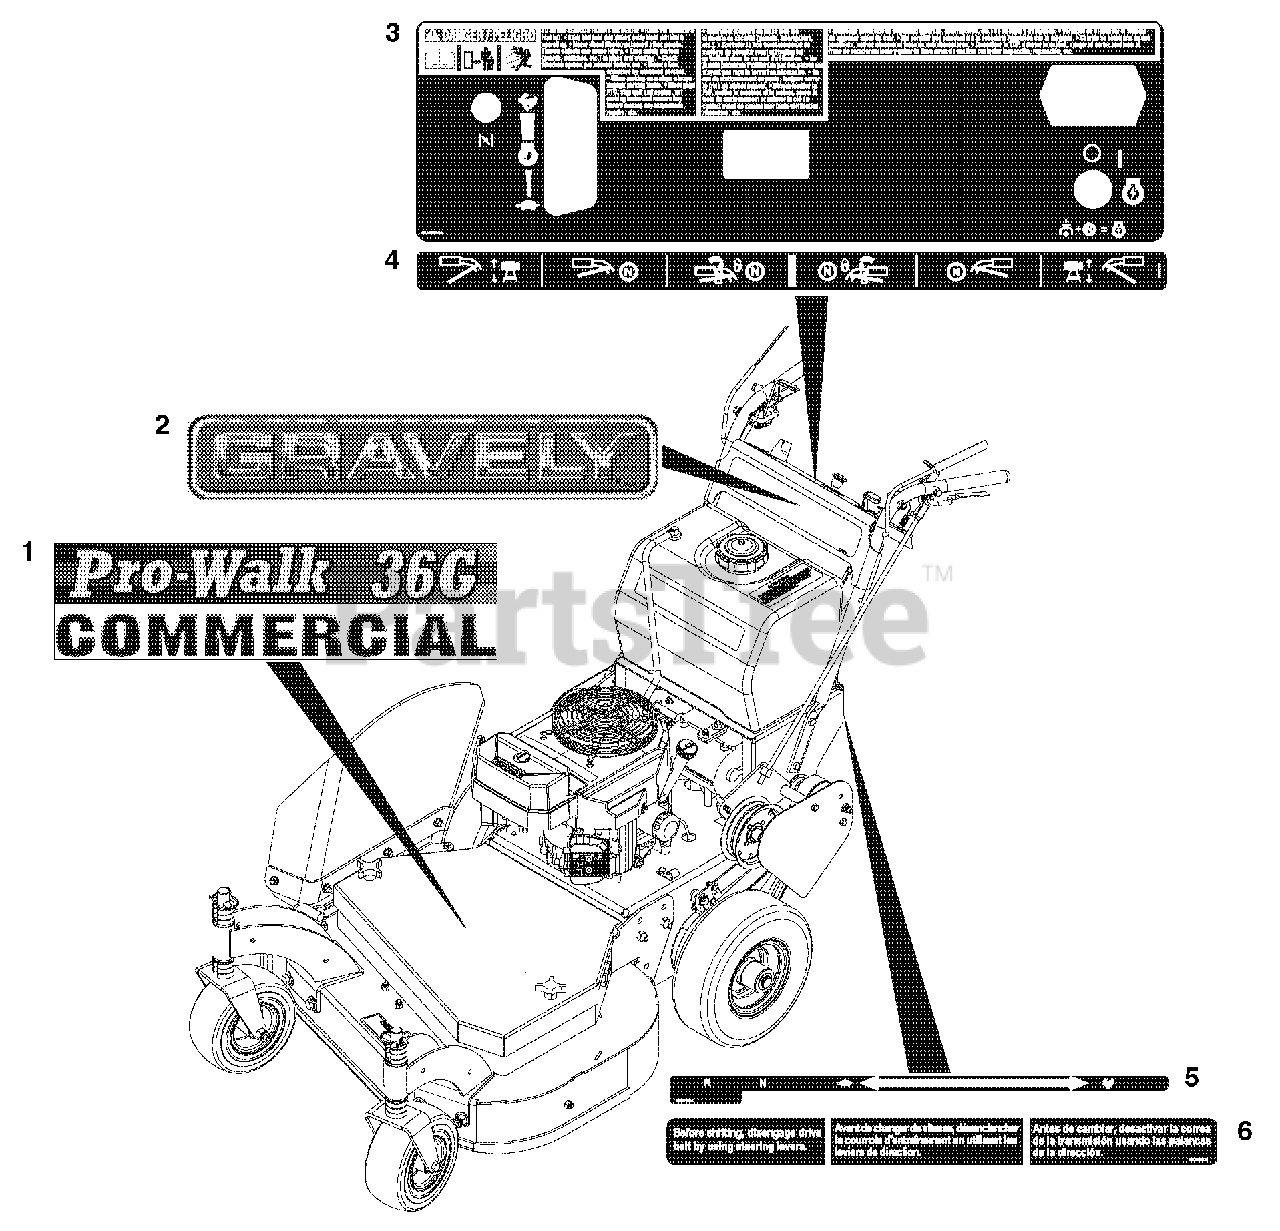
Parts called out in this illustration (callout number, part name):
1	Decal, Pro 1336G (988144)
2	Decal, 15" Gravely Logo
3	Decal, Control GR15
4	Decal, Steer Levers (Gear)
5	Decal, Shift Lever
6	Decal, Declutch-Gear
